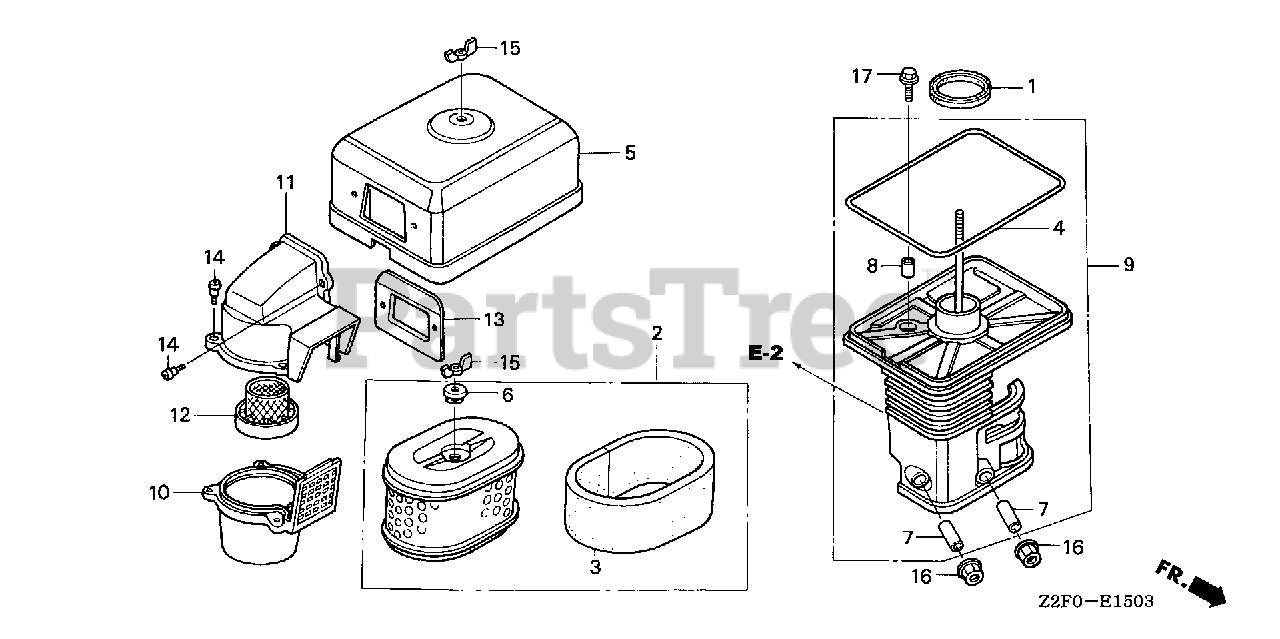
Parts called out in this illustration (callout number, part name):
1	GASKET, ELBOW
2	ELEMENT, AIR CLEANER (DUAL)
3	FILTER (OUTER)
4	GASKET, AIR CLEANER COVER
5	COVER, AIR CLEANER (CYCLONE)
6	GROMMET, AIR CLEANER
7	COLLAR, AIR CLEANER
8	COLLAR B, AIR CLEANER
9	ELBOW, AIR CLEANER
10	CASE, PRE AIR CLEANER
11	CAP, PRE AIR CLEANER
12	GUIDE, PRE AIR CLEANER
13	PLATE, PRE AIR CLEANER
14	BOLT, SPLASH GUARD
15	NUT, TOOL BOX SETTING
16	NUT, FLANGE (6MM)
17	BOLT, FLANGE (6X20)
